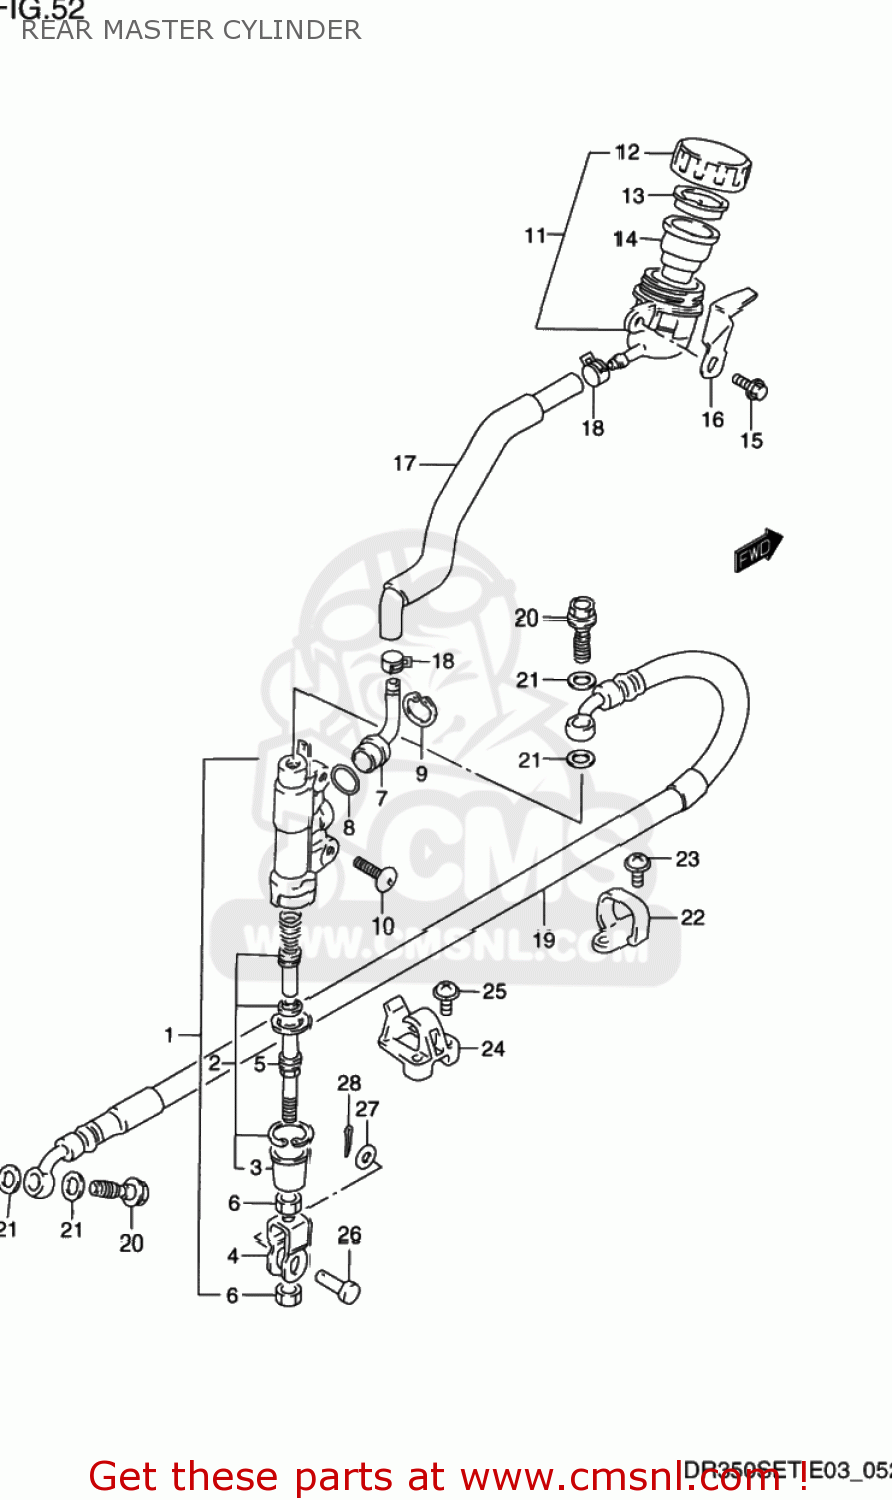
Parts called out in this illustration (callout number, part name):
1	CYLINDER ASSEMBLY,REAR MASTER
2	PISTON/CUP SET
3	BOOT
4	YOKE
5	ROD,PUSH
6	NUT
7	CONNECTOR
8	O RING
9	CIRCLIP
10	SCREW
11	TANK ASSY,RR BRAKE RESERVOIR
12	CAP
13	PLATE
14	DIAPHRAGM
15	BOLT
16	GUARD,RSVR TANK CAP
17	HOSE COMP,RESERVOIR TANK
18	CLIP
19	HOSE,RR BRAKE
20	BOLT UNION
21	WASHER(10X15X1.5)
22	GUIDE,RR BRAKE HOSE
23	SCREW
24	GUIDE,RR BRAKE HOSE
25	SCREW
26	PIN(8X20)
27	WASHER(8.5X13X1.6)
28	PIN 20X15
